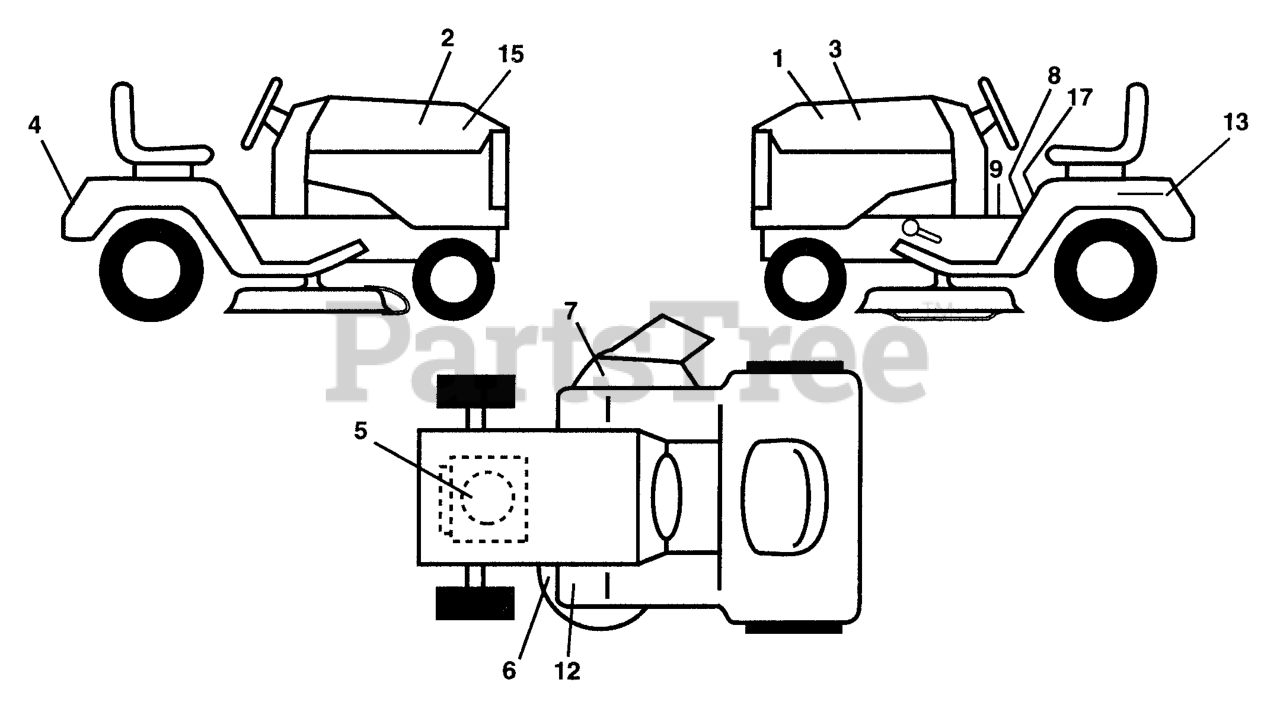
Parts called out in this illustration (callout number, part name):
1	DECAL HOOD LH
2	DECAL HOOD RH
3	DECAL PANEL LH
4	DECAL FENDER NLA
5	DECAL ENGINE
7	DECAL WARNING (ENGLISH/FRENCH)
8	DECAL DASH
15	DECAL PANEL RH
17	DECAL CAUTION
